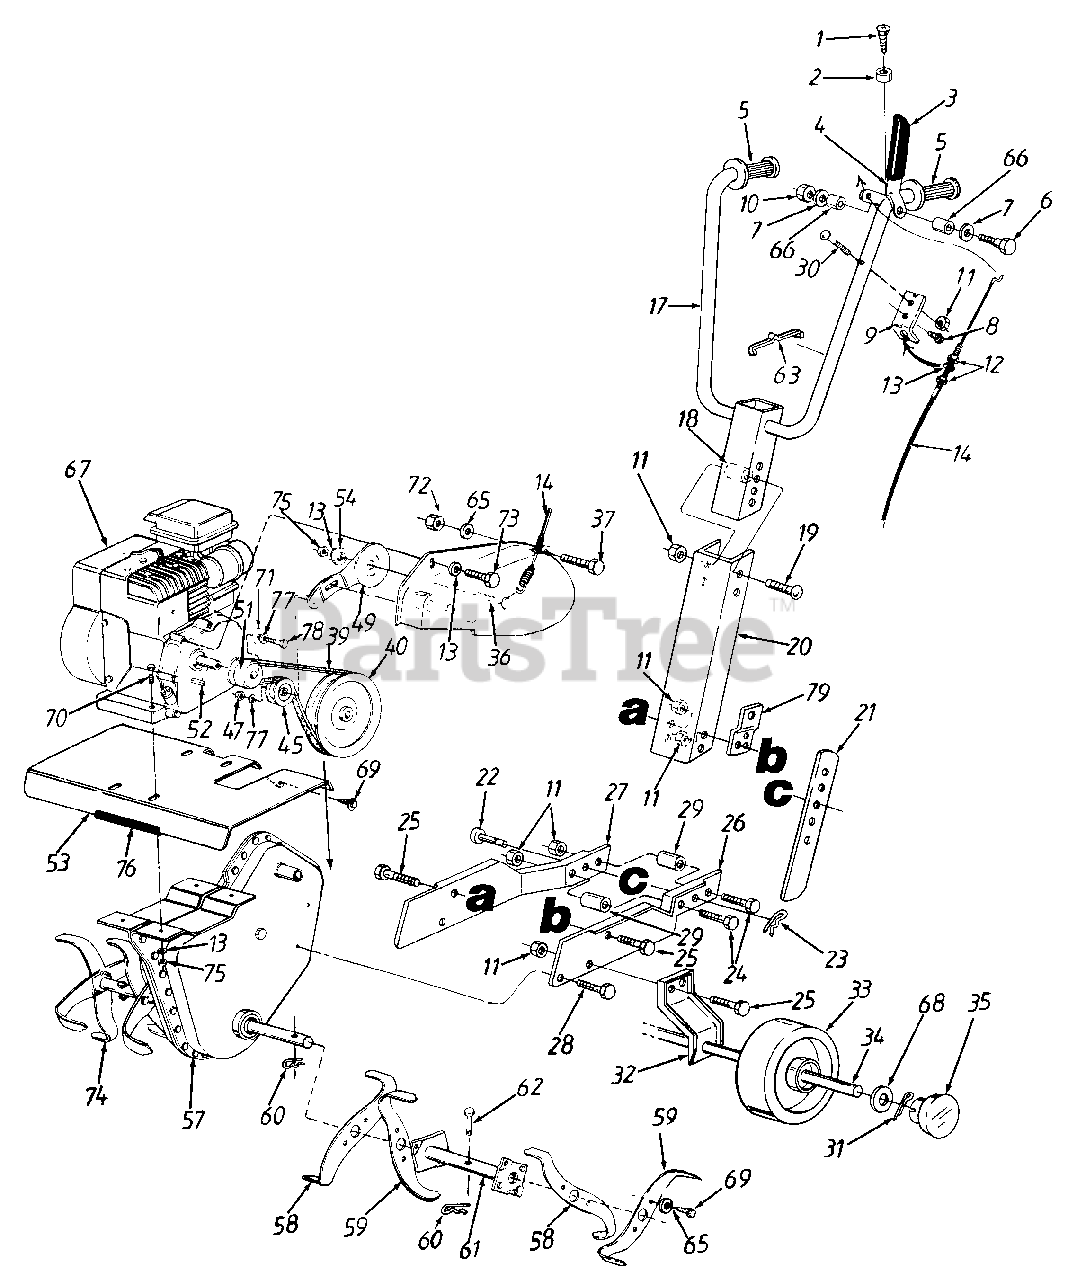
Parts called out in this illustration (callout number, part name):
1	Tap Scr. #10-16 x 1/2" Lg.
2	Rubber Bumper
3	Vinyl Grip
5	Handle Grip
6	Hex Bolt 1/4-20 x 2" Lg.
7	Fl-Wash. 1/4" I.D.
8	Hex Tap Scr. 1/4-20 x 1/2" Lg.
9	Cable Bracket
10	Lock Nut 1/4-20 Thd.
11	Lock Nut 5/16-18 Thd.
12	Hex Jam Nut 5/16-24 Thd.
13	L-Wash. 5/16" I.D.
14	Clutch Control Cable
19	Carr. Bolt 5/16-18 x 2-1/2" Lg.
22	Clevis Pin
23	Hairpin Cotter
24	Hex Bolt 5/16-18 x 1" Lg.
25	Hex Bolt 5/16-18 x 5/8" Lg.
26	L.H. Frame Half
27	R.H. Frame Half
28	Hex Tap. Scr. 5/16-18 x 1/2" Lg.
29	Spacer
30	Hex Bolt 5/16-18 x 1-1/4" Lg.
31	Cotter Pin
32	Wheel Bracket
34	Axle-Wheel
39	V-Belt
40	Pulley-Chain Case
45	Flat Idler Pulley
47	Hex Jam L-Nut 3/8-24 Thd.
49	Idler Arm Ass'y.
51	Engine Pulley
52	Square Key 3/16" x .75" Lg.
57	Chain Case Ass'y. Comp.
58	R.H. Tine Blade
63	Cable Tie-Plastic
65	L-Wash. 1/4" I.D.
67	Engine
68	Fl-Wash. 3/8" I.D.
69	Tap Scr. 1/4-20 x 1/2" Lg.
70	Hex Bolt 5/16-18 x 1-1/2" Lg.
71	Fl-Wash. 3/8" I.D. x 1" O.D.
72	Hex Nut 1/4-20 Thd.
73	Hex Bolt 5/16-24 x .5" Lg.
74	Tine Blade Ass'y. Comp.
75	Hex Nut 5/16-18 Thd.
77	L-Wash. 3/8" I.D.
78	Hex Bolt 3/8-24 x 1" Lg.
79	Belt Cover Bracket
